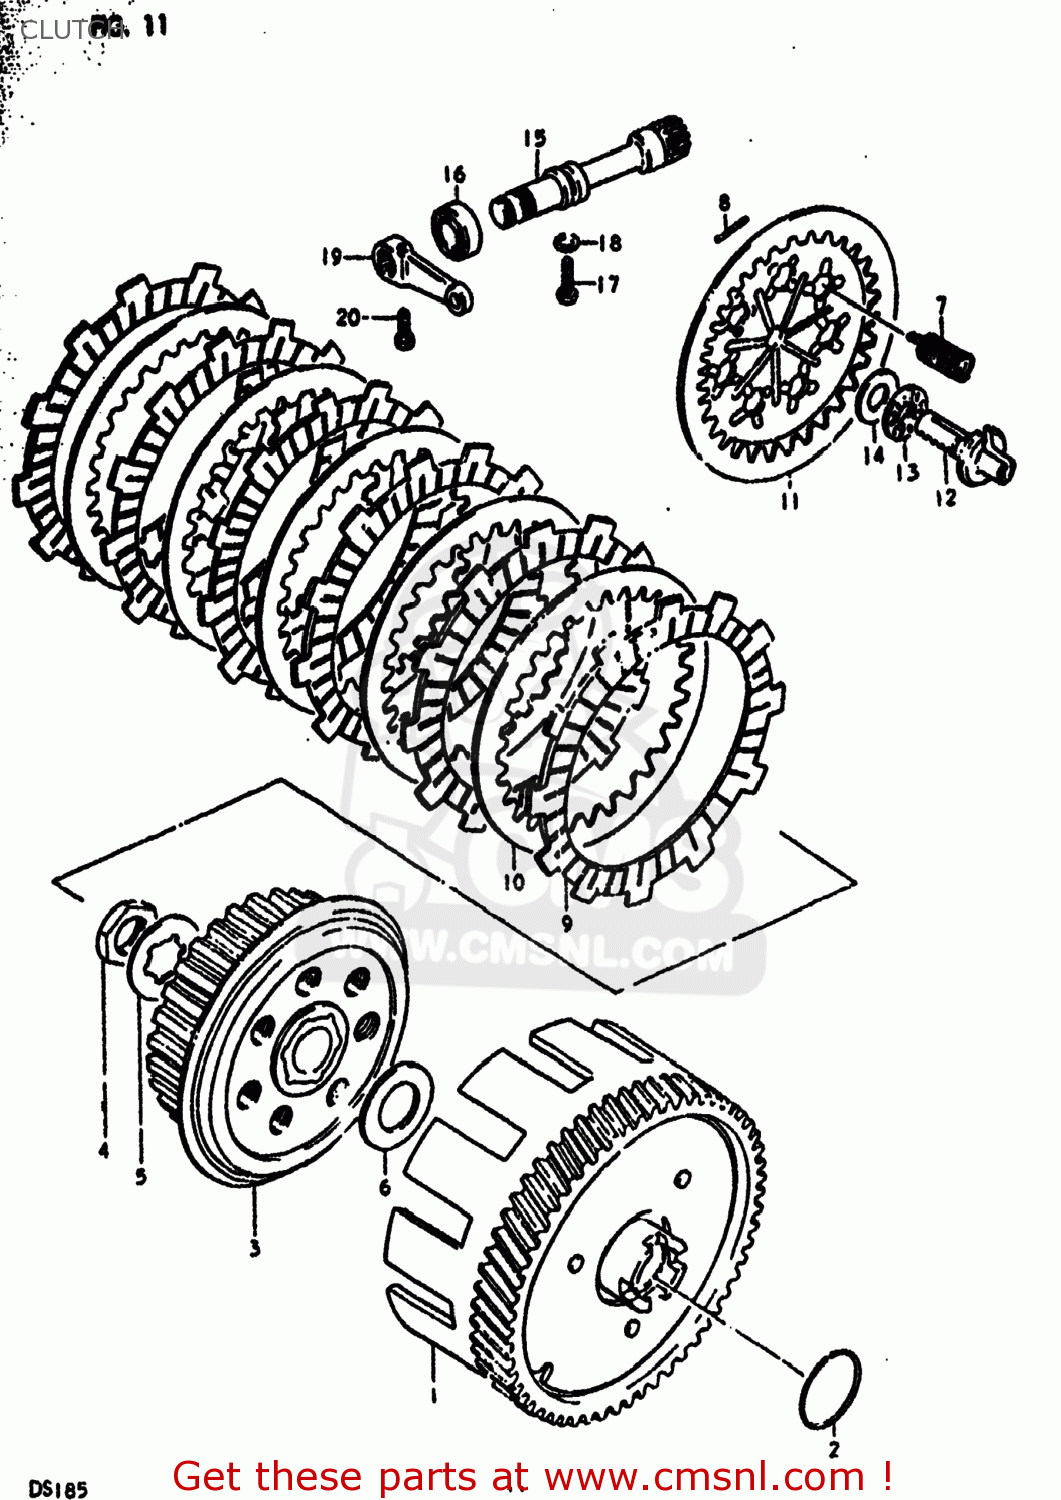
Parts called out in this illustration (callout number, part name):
1	GEAR ASSEMBLY,PRIMARY DRIVE
2	SPRING
3	HUB,CLUTCH SLEEVE
4	NUT
5	WASHER,LOCK
6	WASHER
7	SPRING
8	PIN(2.5X19.8)
9	PLATE,CLUTCH DRIVE
10	PLATE,CLUTCH DRIVEN (NAS)
11	PLATE,CLUTCH PRESSURE
12	RACK,CLUTCH RELEASE
13	BEARING(10X22X2.8)
14	WASHER(10.1X21.4X0.8)
15	PINION,CLUTCH RELEASE
16	OIL SEAL
17	BOLT(6X12)
18	WASHER
19	ARM,CLUTCH RELEASE
20	BOLT
